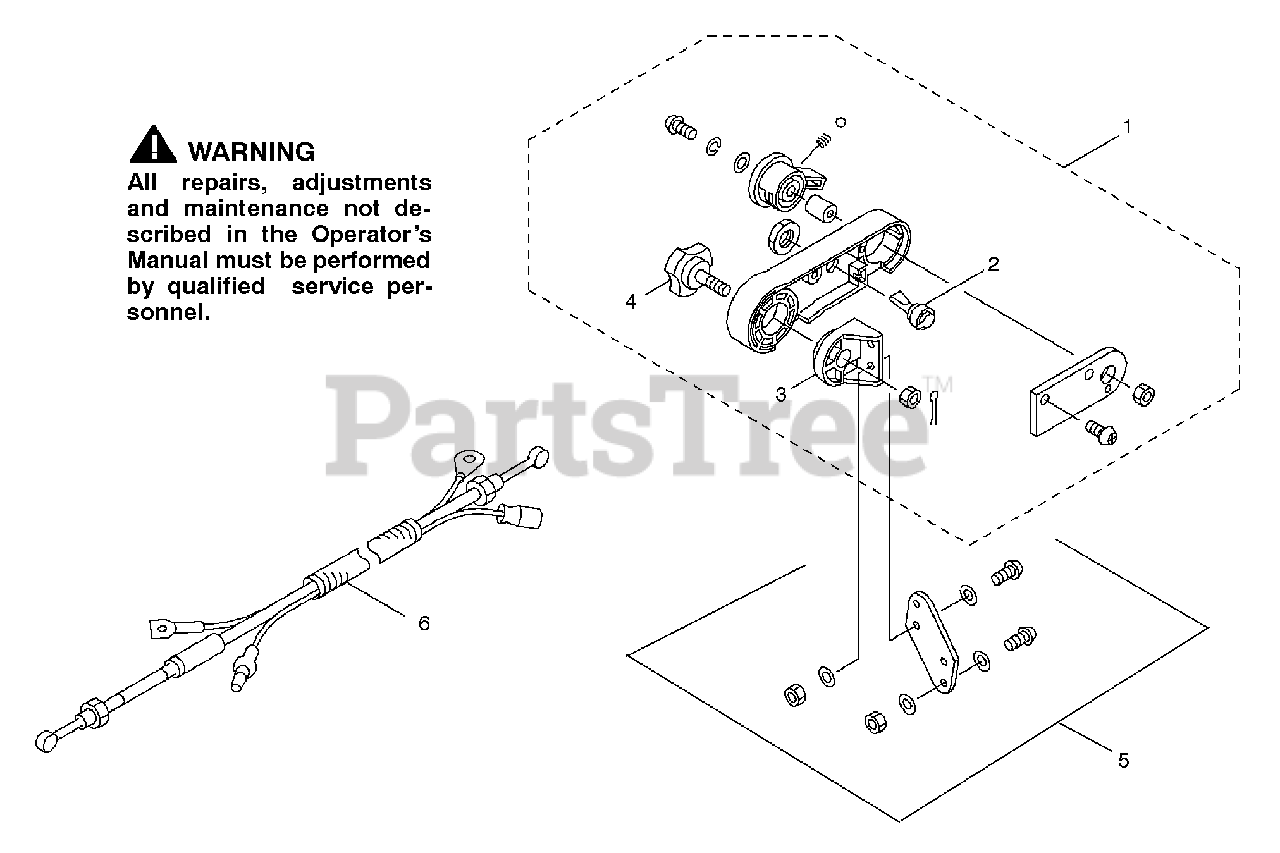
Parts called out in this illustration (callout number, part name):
1	Throttle lever Assy.
4	Knob Bolt
5	Kit - Plate
6	Assy. - Throttle Cable
